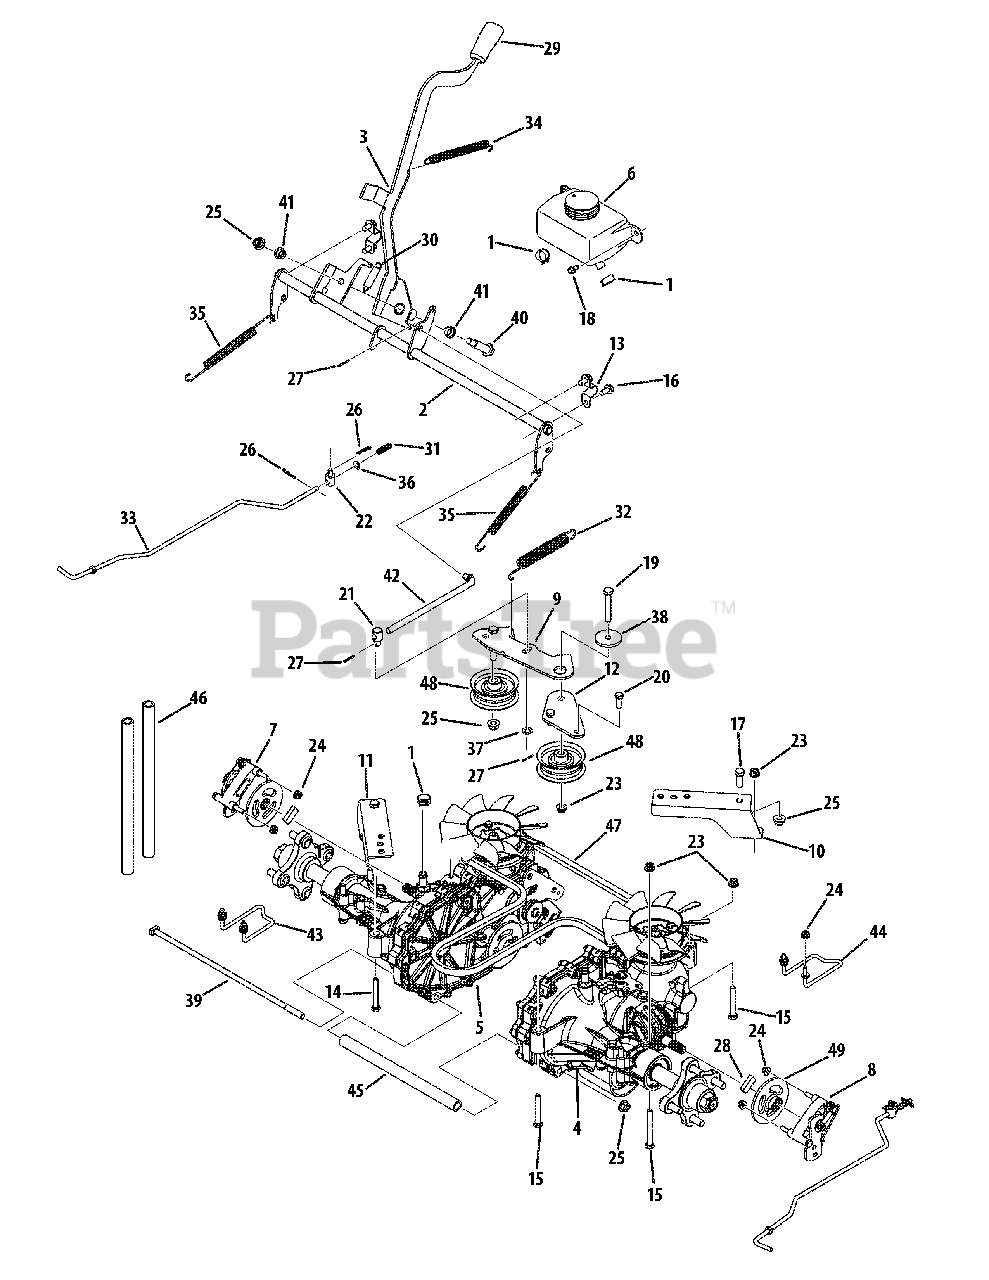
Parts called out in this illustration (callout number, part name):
1	Hose Clamp
2	Brake Shaft Assembly
3	Brake Handle Assembly
4	RH Transmission Assembly
5	LH Transmission Assembly
6	Expansion Tank Assembly
7	LH Brake Assembly
8	RH Brake Assembly
9	Idler Bracket
10	RH Mount Bracket
11	LH Mount Bracket
12	Idler Mount Plate
13	Shaft Mount Bracket
14	Hex Screw, 5.16-18 x 2.75
15	Hex Screw, 5.16-18 x 2.25
16	Hex Washer Screw, 5.16-18 x .750
17	Hex Screw, 3.8-16 x 1.00
18	Hex Washer Screw, 1.4-20 x .500
19	Hex Screw, 3.8-16 x 2.25
20	Hex Screw, 5.16-18 x .875
21	Ferrule, 3.8-24 x .375
22	Ferrule, .325 x .312
23	Flange Lock Nut, 5.16-18
24	Flange Lock Nut, 1.4-20
25	Flange Lock Nut, 3.8-16
26	Cotter Pin, .072 x 1.13
27	Cotter Pin, 3.32 x .750
28	Brake Pad
29	Selector Handle
30	Extension Spring, .48 x 2.03
31	Compression Spring, .405 x 1.17
32	Extension Spring, .75 x 6.02
33	Transmission Bypass Lever Wire
34	Extension Spring, .50 x .6.37
35	Extension Spring, .500 x 7.0
36	Spring Washer, .265 x .562 x .025
37	Thrust Washer, .375 x .70 x .030
38	Shoulder Spacer, .884 x .190
39	Rod, .328 x 14.00
40	Shoulder Screw, .498 x 1.635
41	Flange Bearing, .500 x .34
42	Disenage Brake Rod
43	LH Rod Keeper
44	RH Rod Keeper
45	Transmission Spacer, 10.5
46	Fuel Hose, 1.2 x 12.00
48	Flat Idler Pulley, 2.75
49	Brake Disc
